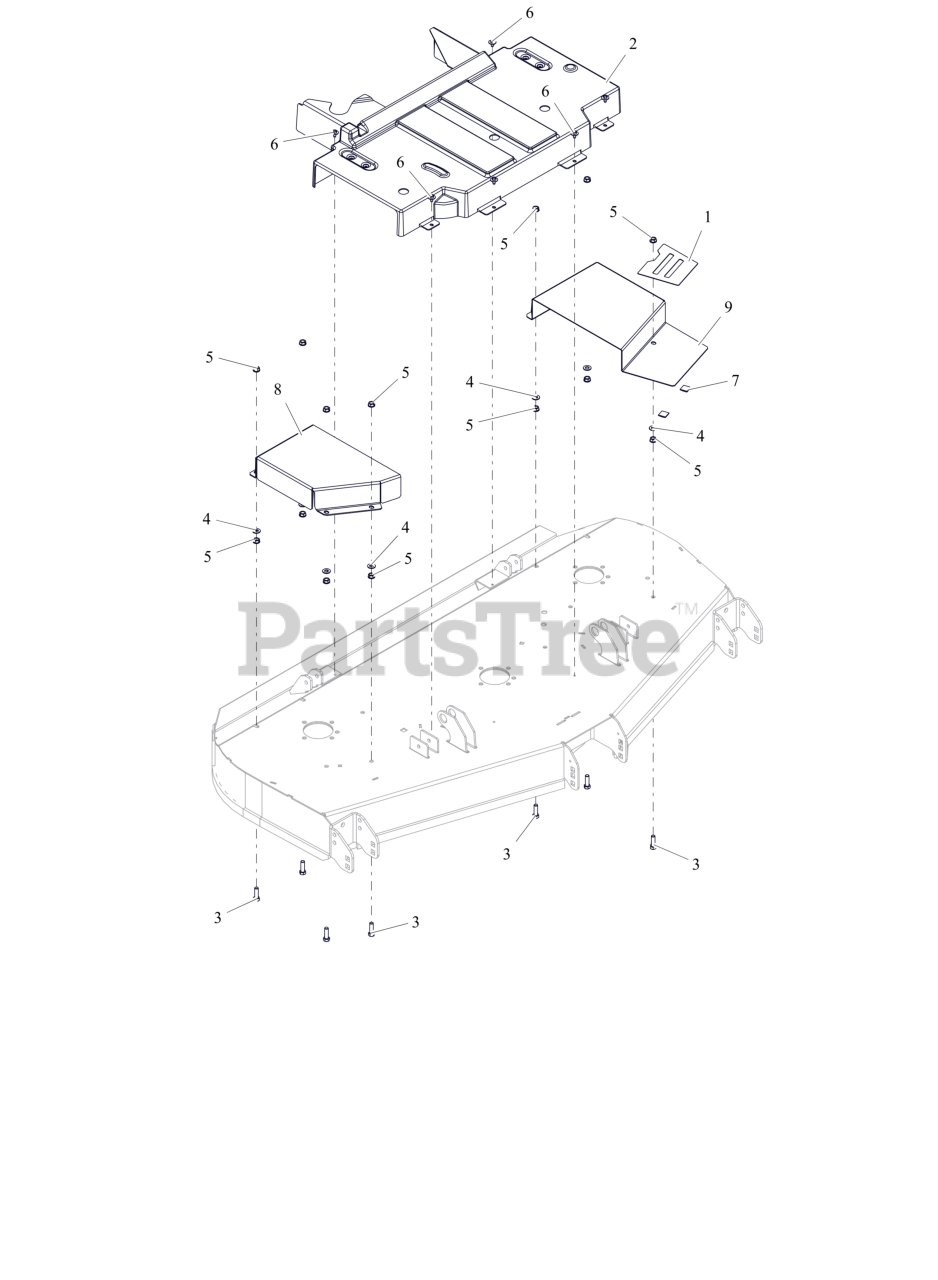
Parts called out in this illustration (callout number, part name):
1	GRIP TAPE 52-60 BELT COVER
2	GUARD, CENTER DECK SPINDLE CE
3	BLT, HEX .38-16X1.25 G5 ZCC
4	WSHR,FLT .406X.812X.065 ZCC
5	NUT, SPNLK-FLG .38-16 G5 ZCC
6	SCR, TAP .25-20X.50 LG HWH ZCC
8	GUARD, BELT 52" RIGHT CE (ORANGE)
9	GUARD, BELT 60" LEFT CE (ORANGE)
